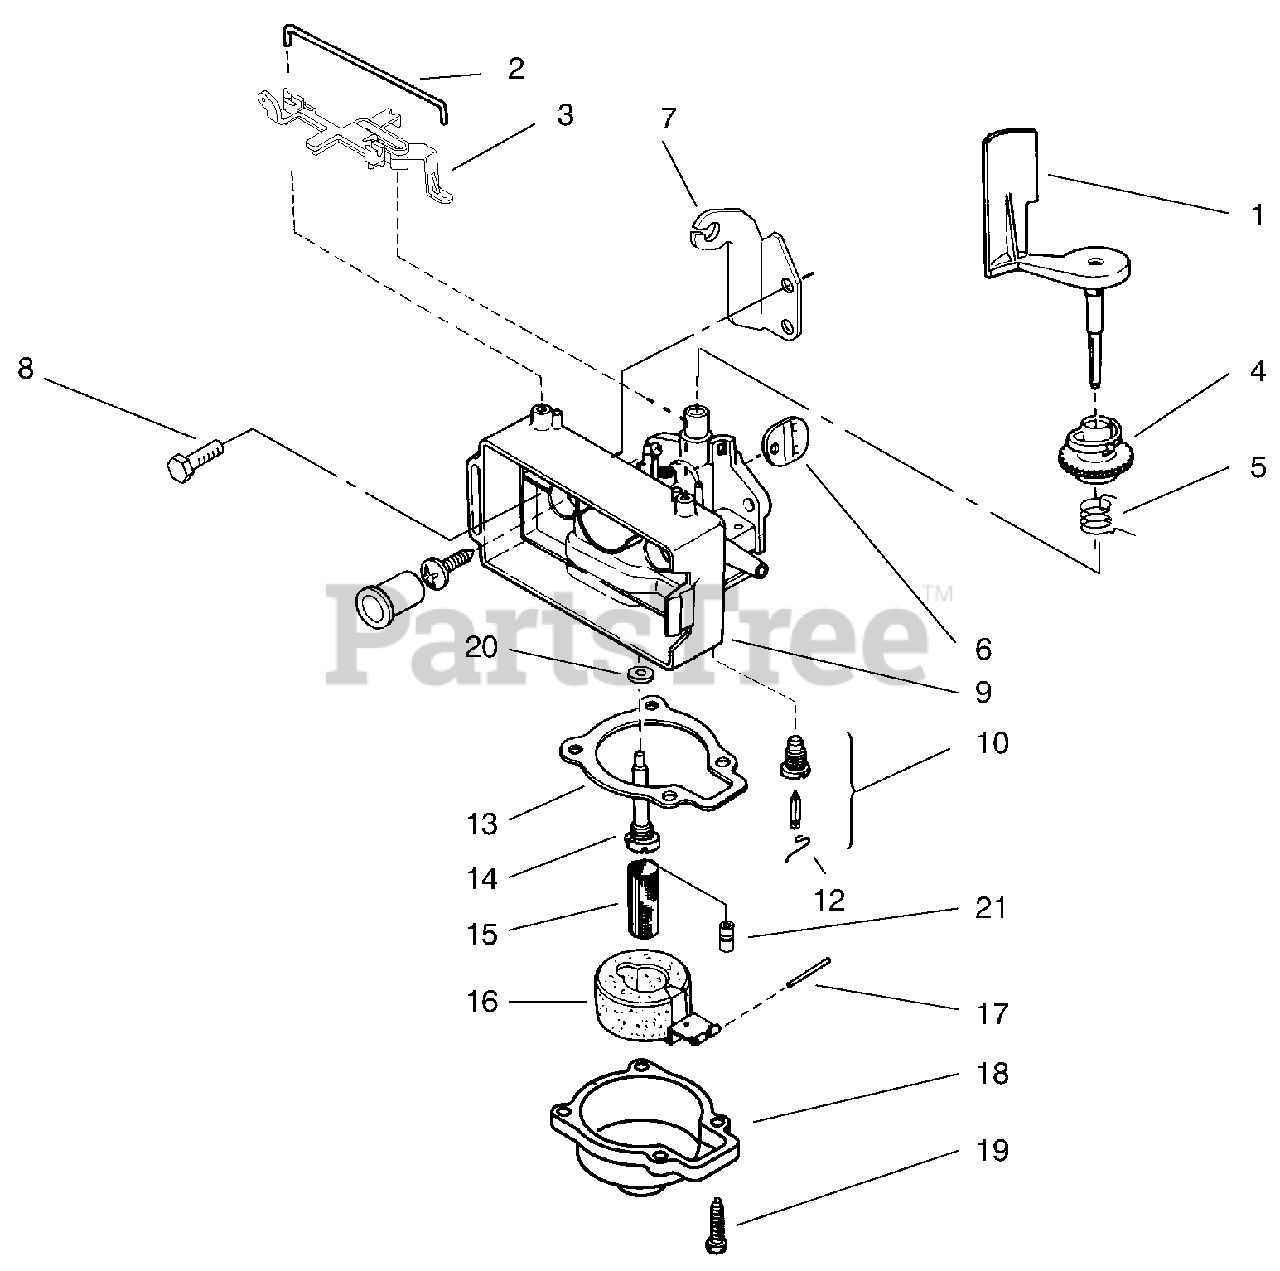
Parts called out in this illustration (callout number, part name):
1	Air Vane & Shaft
2	Retainer-Speed Control
3	Lever-Speed Adjust
4	Collar-Air Vane
5	Spring-Governor
6	Disc-Throttle
7	Bracket-Throttle Control
9	Carburetor Body
10	Kit-Float Valve, Body & Seat (Incl. Ref. #12)
12	Spring
13	Gasket
15	Filter-Fuel
16	Float & Arm Assembly
18	Float Chamber
21	Main Jet
